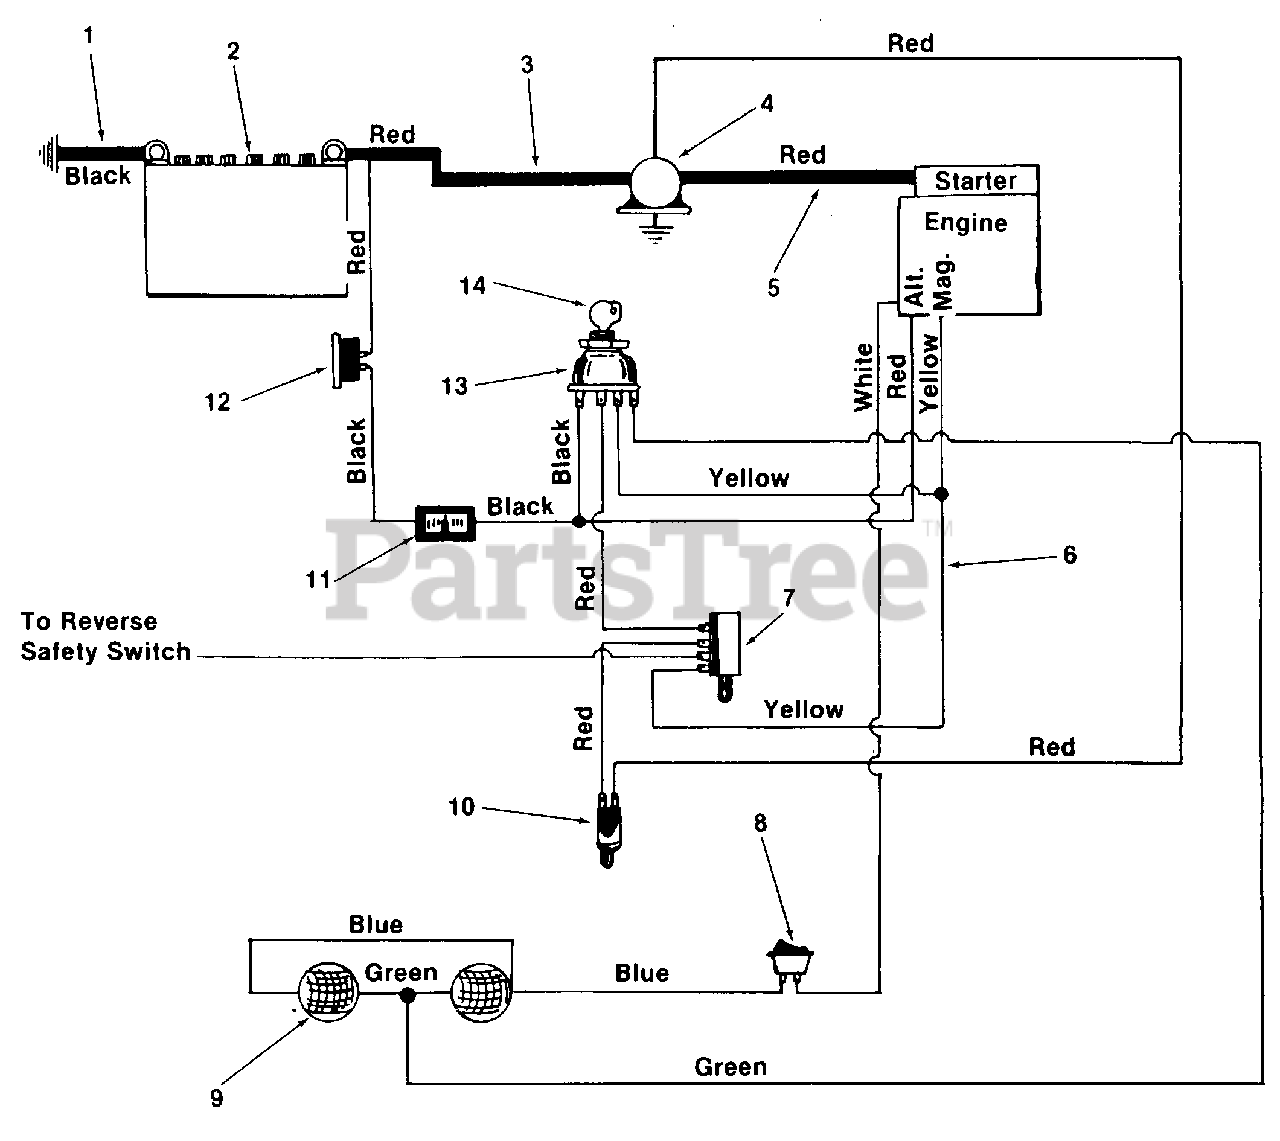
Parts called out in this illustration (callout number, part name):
1	Electric Ground Wire
2	12V-Battery
3	Electric Wire
4	Solenoid
5	Electric Wire
6	Wire Harness
7	Safety Switch
8	Light Switch
9	Head Lights
10	Safety Switch
11	Ammeter
12	Circuit Breaker
13	Ignition Switch
14	Ignition Key
